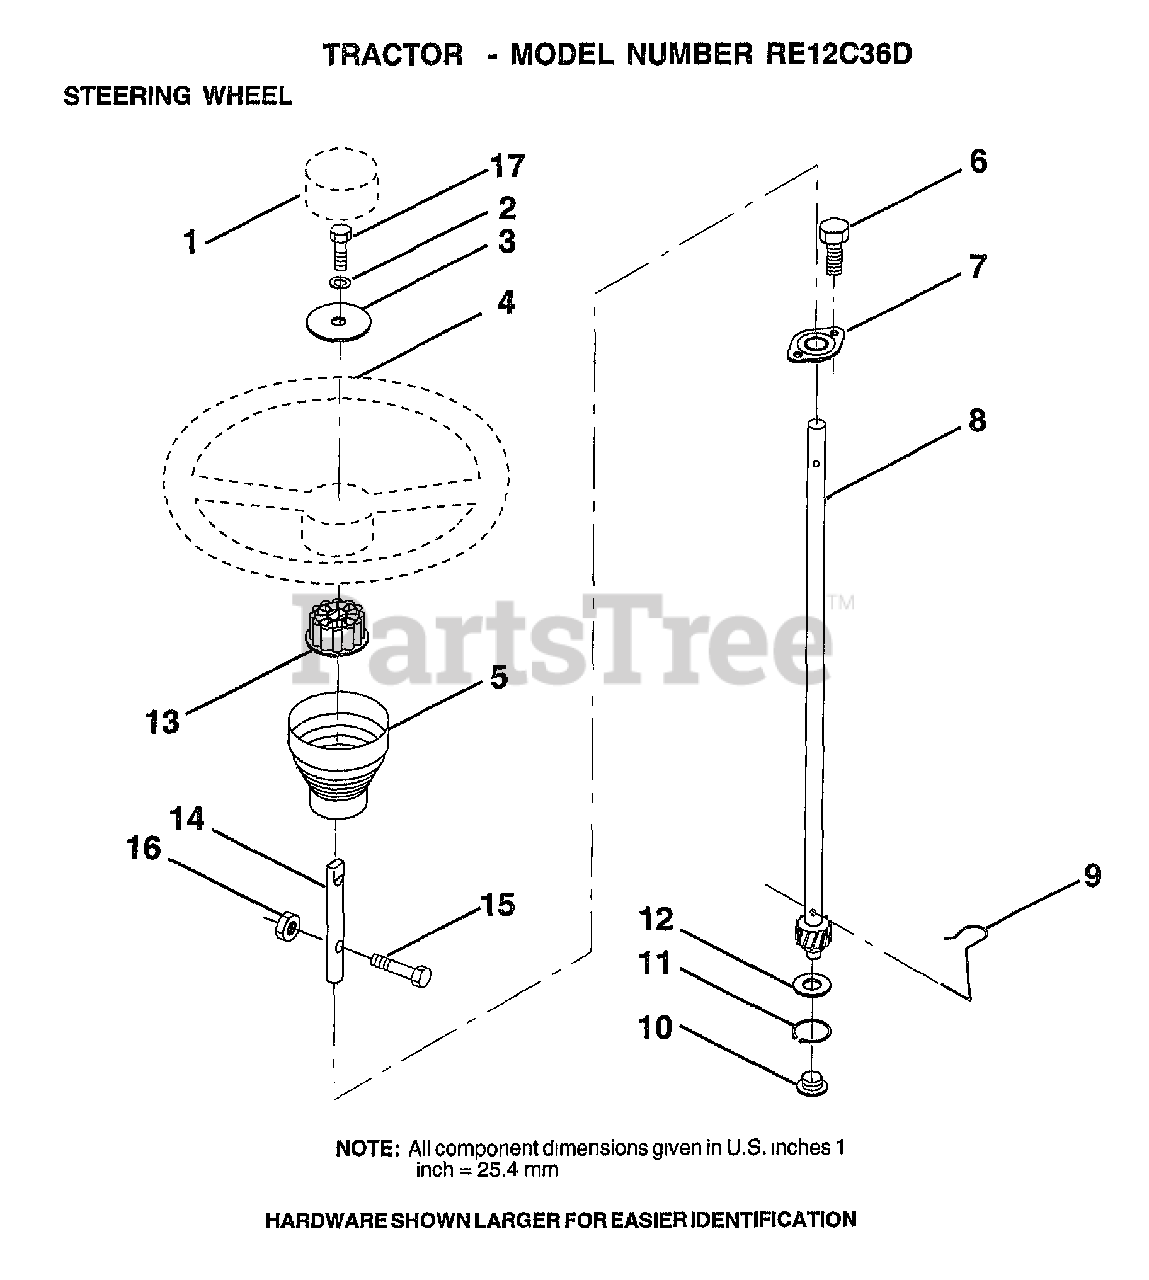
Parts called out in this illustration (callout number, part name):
1	ST WHL INSERT CAP
2	LOCKWASHER
3	WASHER
5	SLEEVE STEERING
6	"SCREW-TT,10-32 FL"
7	BUSHING.STR.623
8	SHAFT.STEERING.LR
9	STEERING CLIP
10	BUSHING STEER LWR
11	RING
12	WASHER LT
13	ADAPTER LT
14	EXT SHAFT STEERIN
15	BOLT
16	NUT
17	BOLT
